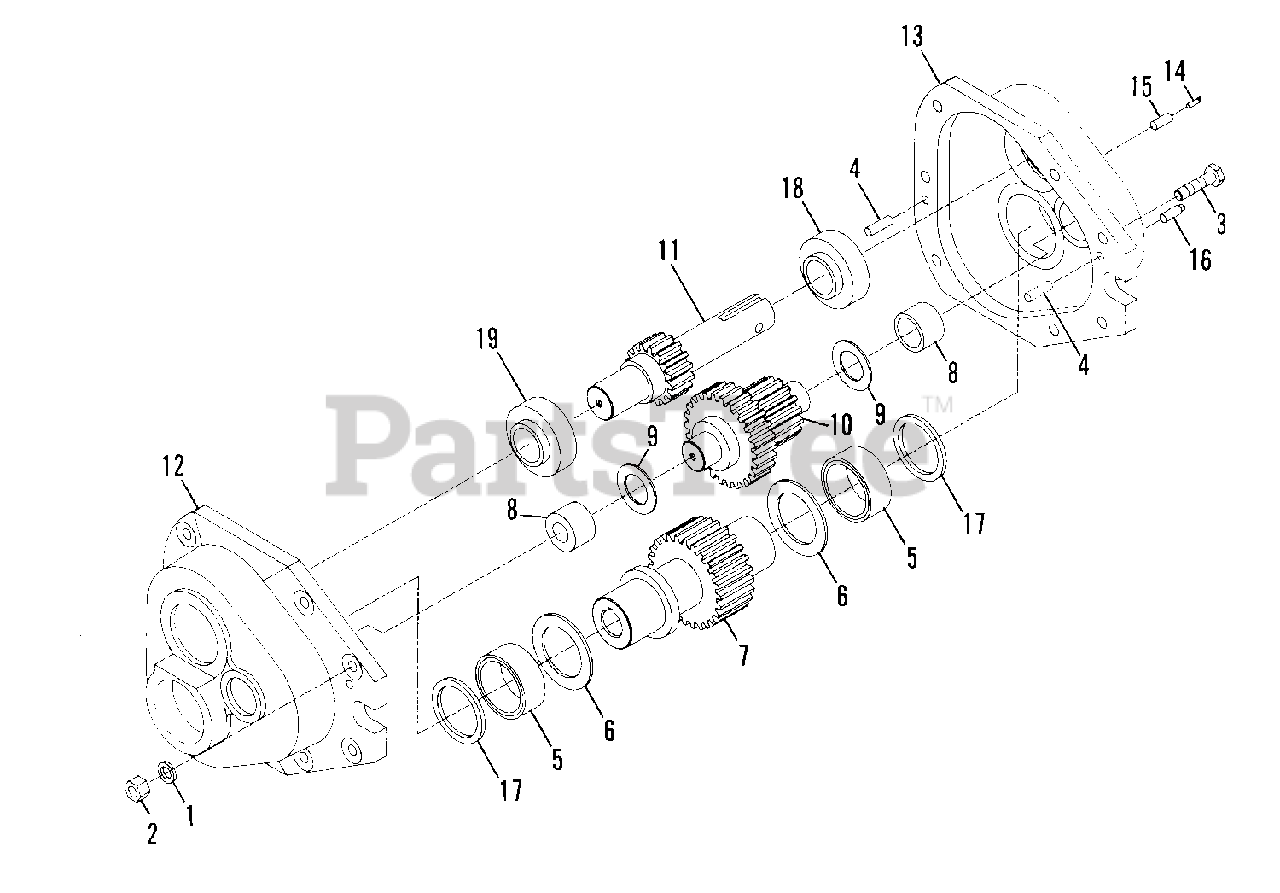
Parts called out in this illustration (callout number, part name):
1	LOCKWASHER, 5/16
2	NUT, Hex, 5/16-18
3	CAPSCREW, Hex Head, 5/16-18 x 1-1/4
4	PIN, Dowel, 1/4 x 1/2
6	THRUST RACE
7	GEAR, Output
9	THRUST RACE
10	GEAR, Idler
11	GEAR, Input
12	GEARBOX, Snowthrower-Front
13	GEARBOX, Snowthrower-Rear
14	FITTING, Lube, 1/4-18, 90 Degrees
15	FITTING, Reducer, 1/4 Male x 1/8 Female
16	PLUG, Pipe Square Head, 1/4 NPT
18	BEARING, Ball
19	BEARING, Ball
